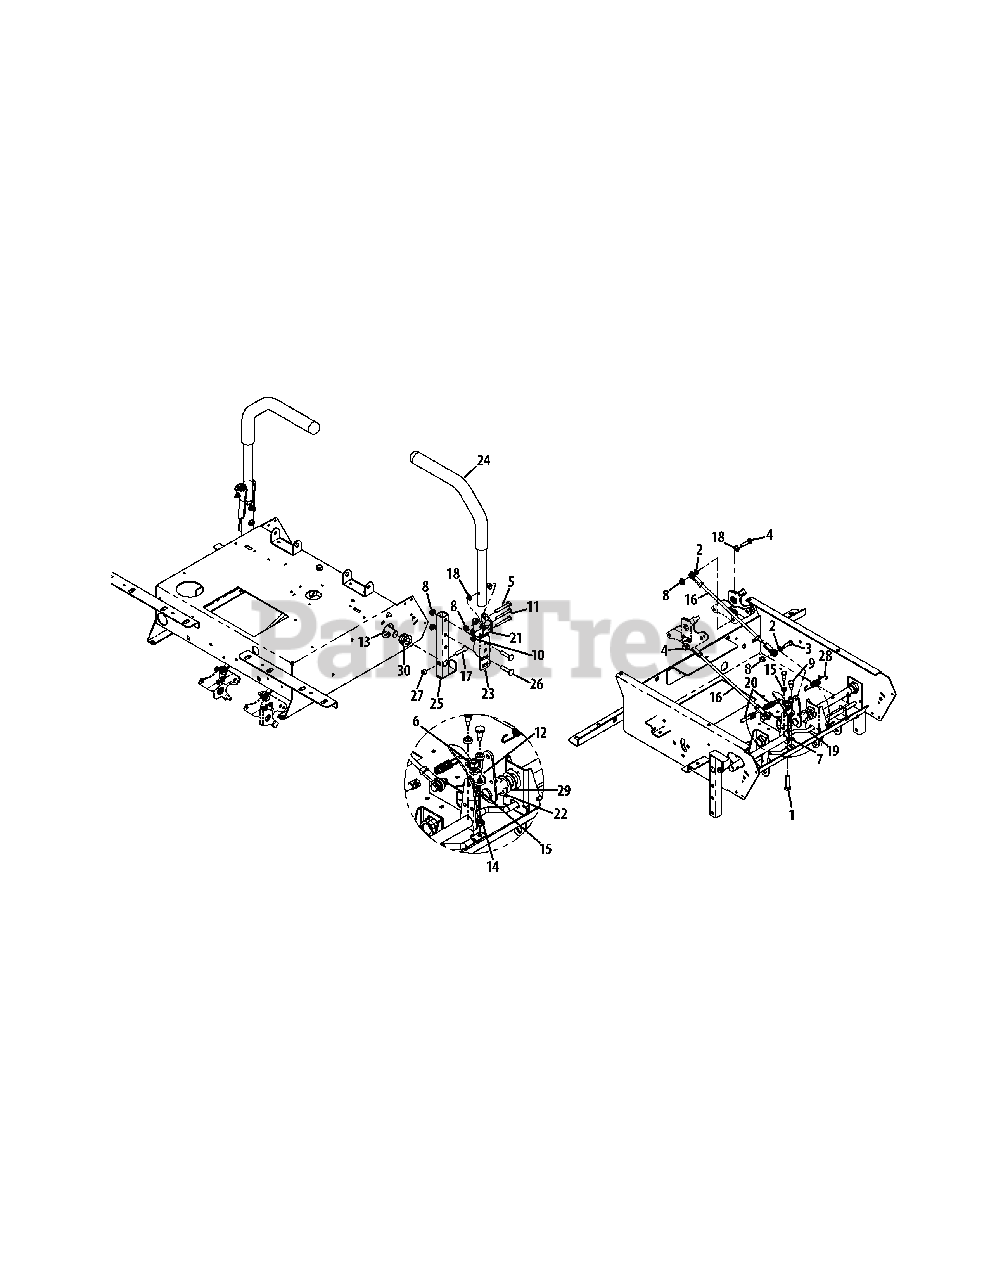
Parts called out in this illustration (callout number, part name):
1	Hex Cap Screw, 3/8-16 x 1-1/2
2	Flat Washer, 5/16
3	Hex Head Cap Screw, 5/16-18 x 1.00
4	Hex Screw, 5/16-18 x 1-1/4
5	Hex Cap Screw, 5/16-18 x 2.00
6	Flange Lock Nut, 3/8-16
7	Flat Washer, 1.4 x .630 x .0515
8	Lock Nut, 5/16-18
9	Shoulder Screw, 1/4-28
10	Hex Flange Lock Nut, 1/4-20
11	Hex Cap Screw, 1/4-20 x 2.00
12	Brake Lever Plate
13	Steering Input Shaft Assembly
14	Spacer, .385 x .625 x .869
15	Spacer, .380 x .563 x .196
16	Steering Link Rod
17	Socket Head Capscrew, 5/16-18 x 1.25
18	Bushing, .310 x .172 x .688 x .06
19	Control Lock Rod
20	Control Cable Lock Out
21	Spacer, .25 x .38 x 1.13
22	E-Clip Retainer Ring
23	Lapbar Pivot Bracket
24	Lapbar Handle/Grip Assembly
25	Pivot Bracket Weldment
26	Carriage Bolt, 5/16-18 x 1.50
27	Nylock Nut, 5/16-18
28	Extension Spring, .544 x 3.35
29	Flat Washer, .793 x 1.24 x .060
30	Hex Flange Bearing, .752
